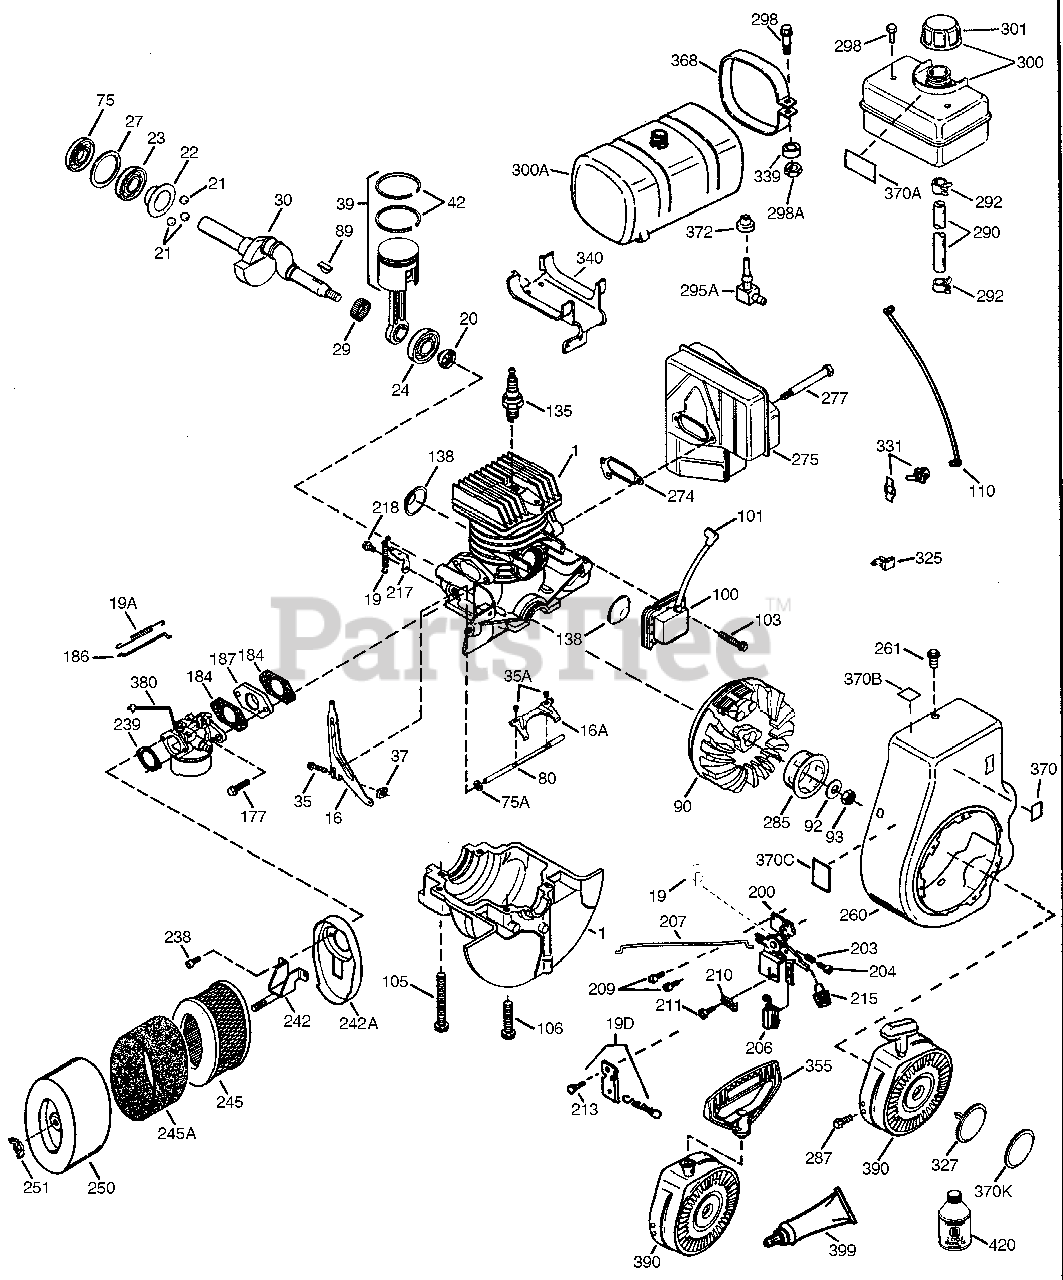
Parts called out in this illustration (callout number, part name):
1	"Cylinder (Incl. 75A, 105, 106 & 138)
16	Governor Lever
16A	Governor Follower Arm
19	Speed Control Spring
19A	Backlash Spring
20	Oil Seal
21	Ball Bearing
22	Slide Ring
23	Ball Bearing
24	Ball Bearing
27	Bearing Retainer
29	Bearing Strip (31 Needles)
30	Crankshaft
35	Screw, 10-32 x 3/4"
35A	Screw, 4-40 x 1/4"
37	Lock Nut, 10-32
39	Piston & Rod Ass'y. (Incl. 29 & 42)
42	Ring Set
75	Oil Seal
75A	Oil Seal
80	Governor Shaft
89	Flywheel Key
90	Flywheel
92	Belleville Washer
93	Flywheel Nut
100	Solid State Ignition
101	Spark Plug Cover
103	Screw, Torx T-15, 10-24 x 15/16"
105	Screw, 5/16-18 x 2-3/16"
106	Screw, 5/16-18 x 1-5/8"
110	Ground Wire
135	Resistor Spark Plug (RCJ8Y)
138	Port Cover
177	Screw, 5/32 Allen, 1/4-20 x 1"
184	Carburetor Gasket
186	Governor Link
200	Control Bracket (Incl. 203, 204, 206)
203	Compression Spring
204	Screw, 5-40 x 7/16"
206	Terminal
207	Throttle Link
209	Screw, 10-32 x 1/2"
215	Control Knob
238	Screw, 10-32 x 1/2"
239	Air Cleaner Gasket
242	Air Cleaner Bracket
242A	Air Cleaner Bracket Base
245	Air Filter (Paper) also available in Packaged Part #740027B
245A	Poly Pre-Filter (also available in Pa ckaged Part #740027B)
250	Air Cleaner Cover
251	Wing Nut, 1/4-20
260	Blower Housing
261	Screw, 5/16-18 x 5/8"
274	Exhaust Gasket
275	Muffler
277	Screw, 5/16-18 x 3-13/64"
285	Starter Cup
287	Screw, 8-32 x 21/64"
290	Fuel Line
292	Fuel Line Clamp
325	Wire Clip
370A	Lubrication Decal
370B	Fuel Mix Decal
370C	Speed Control Decal
370K	Starter Decal
380	Carburetor (Incl. 184)
390	Rewind Starter (NOTE: This engine co uld hav e been built with 590738 star ter. Refer to the design of the rope pulley strength ribs for part identif ication. Individual starter parts do not interchange. Refer to service b ulletin 116).
399	Gasket Eliminator (Loctite 515)
420	2-Cycle Oil with Fuel Stabilizer - 8 oz.
